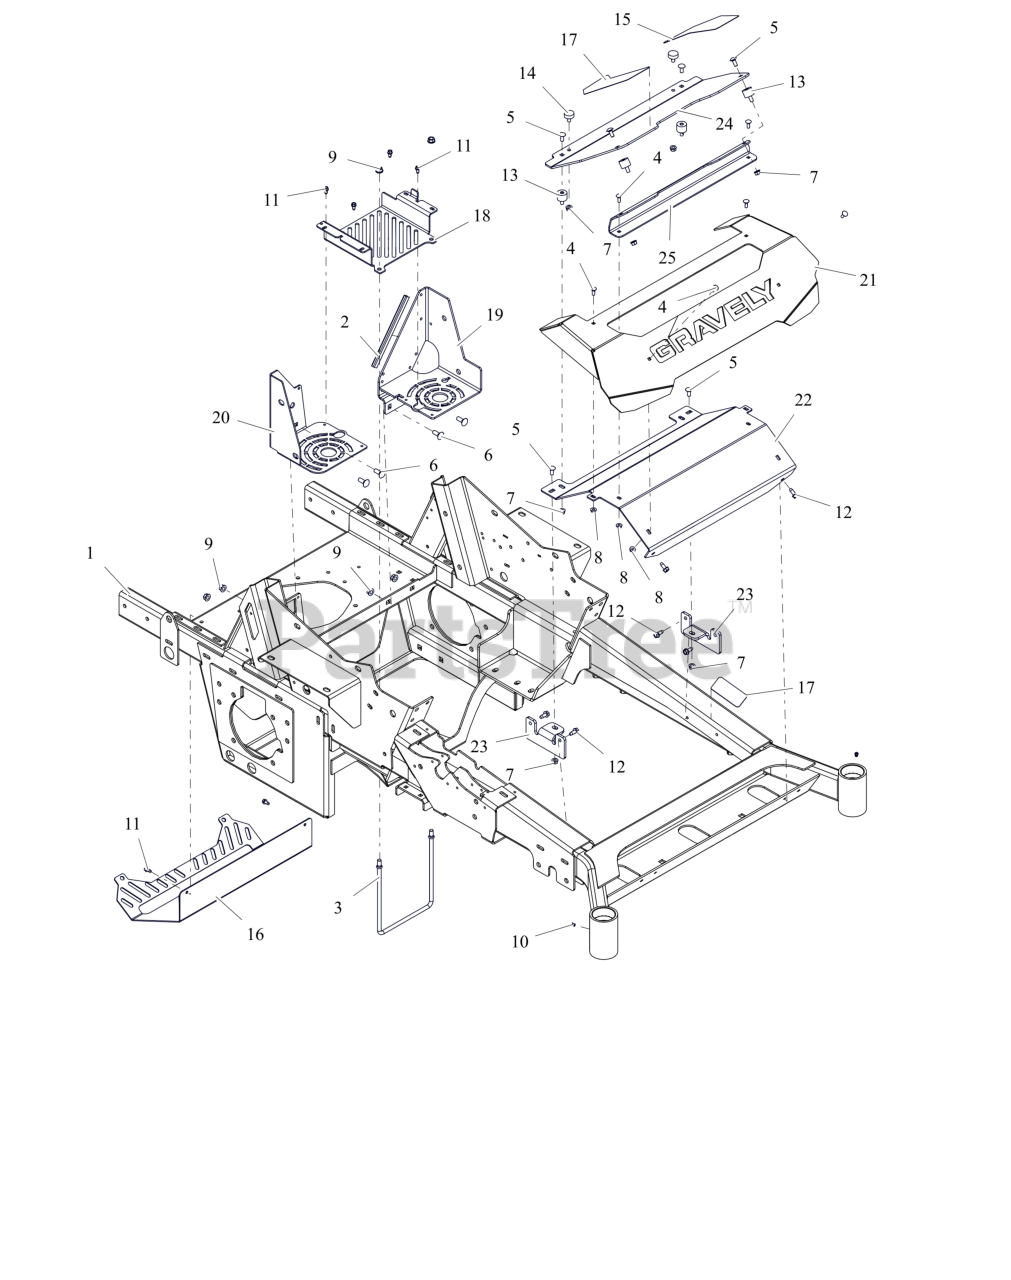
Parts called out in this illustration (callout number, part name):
1	WLDMT, 48", 52", 60" FRAME (RED)
2	STRIP, COWL
3	ROD, BRAKE MTG
4	BLT, RHSN .25-20X.750 G5 ZCC
5	BLT, RHSSN.31-18X.750 G5 ZCC
6	BLT, RHSN .38-16X1.00 G5 ZCC
7	NUT,SPNLK-FLG .31-18 G5 ZCC
8	NUT-LK-CTR-FLG .25-20 ZC120
9	NUT-LK-CTR-FLG .375-16 GF ZCC
10	FTG, .25-28 FLUSH MNT GREASE
11	SCR-TAP .25-20X.50 HWH ZCC
12	SCR,TAP .312-18X.75 HWH TR ZCC
13	BUMPER,STUD MNTD W/FEMALE INSR
14	BUMPER, RUBBER
15	ANTI-SKID, LH FOOTREST
16	GUARD, MUFFLER (BLACK)
17	ANTI-SKID, FRAME STEP
18	TRAY- BATTERY
19	GUSSET-LH BATTERY TRY/ROPS-RED
20	GUSSET- FAN GUARD/ROPS - RED
21	BMPR-PT300-500 FRT FTRST/ -RED
22	BRKT-FRT BUMPER MTG/BACKER-BLK
23	BRKT, FOOTREST MTG (RED)
24	FOOTREST, PT300-500 (RED)
25	BRKT, FOOTREST SUPPORT (BLK)
